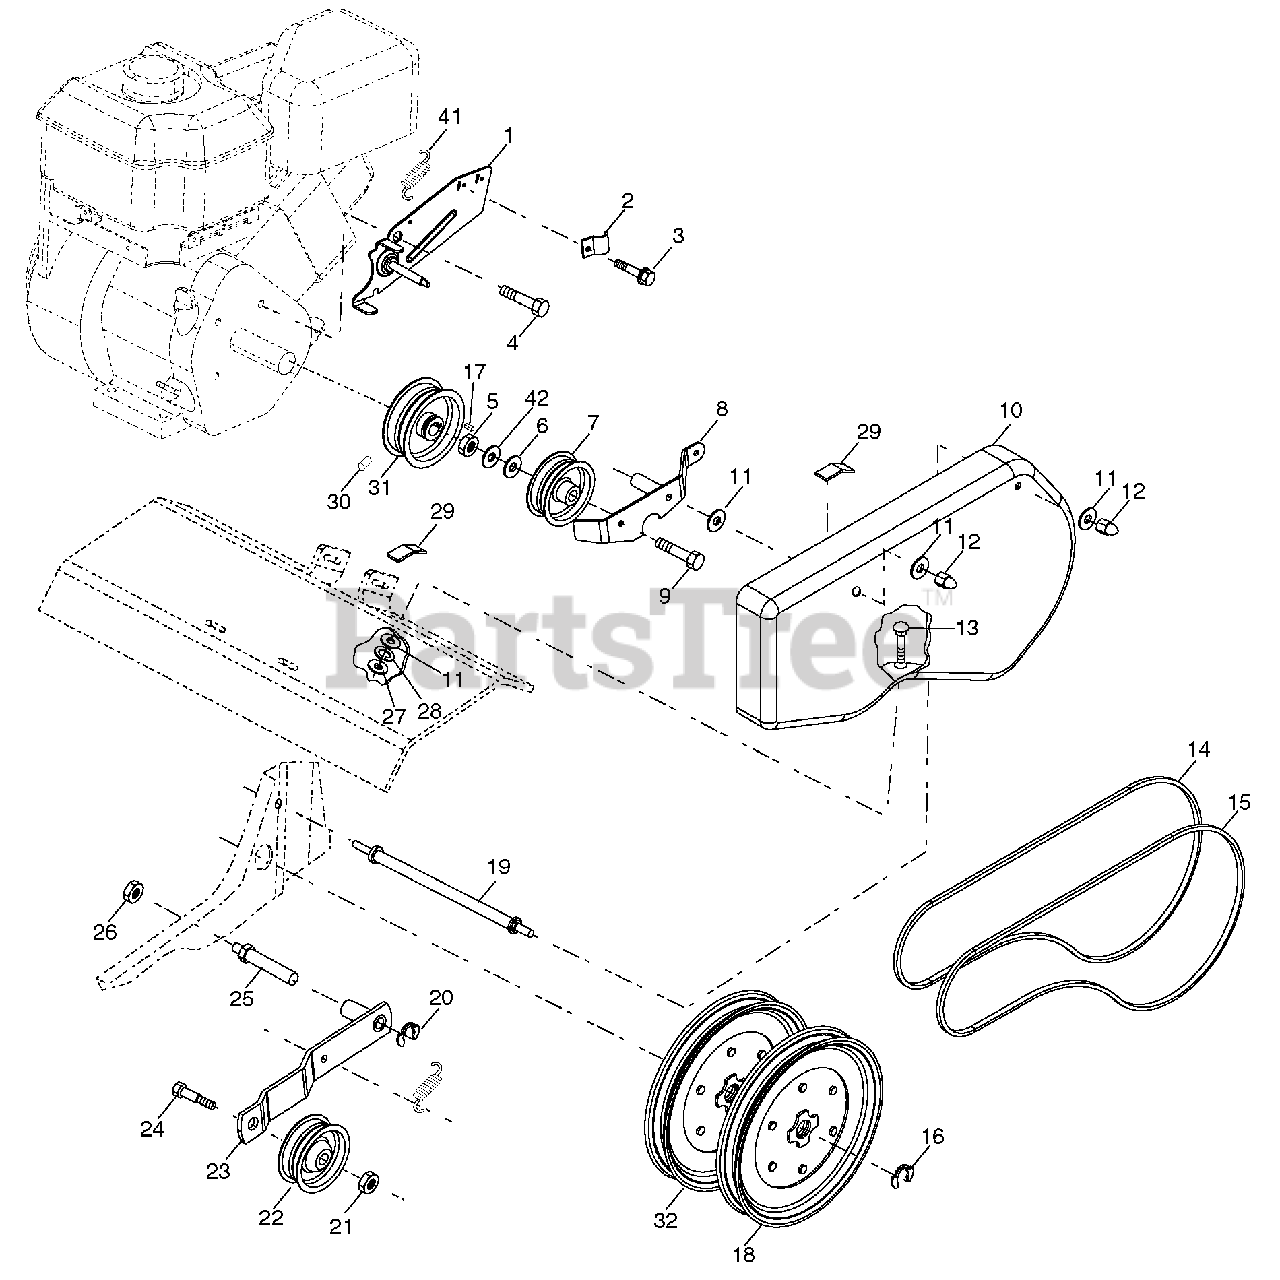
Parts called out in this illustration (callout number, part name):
1	Bracket Assembly, Belt Guard
2	Clip, Cable
3	Screw, Hex Washer Head, Slotted, Thread Cutting #10-24 x 1/2
4	Bolt, Hex Head 1/2-20 x 3/4
5	Locknut, Hex 3/8-16
6	Washer 13/32 x 13/16 x 16 Gauge
7	Pulley, Idler, Reverse
8	Reverse Idler Arm Assembly
9	Bolt, Hex Head 3/8-16 x 1-3/4
10	Guard, Belt
11	Washer 9/32 x 5/8 x 16 Gauge
12	Nut, Hex, Cap 1/4-20
13	Bolt, Carriage 1/4-20 x 3/4
14	V-Belt (Forward Motion)
15	V-Belt (Reverse)
16	Ring, Retainer
17	Key, Square
18	Pulley, Flat, Transmission
19	Bolt, Belt Guard
20	Ring, Klip
21	Nut, Hex, Jam 3/8-16
22	Pulley, Idler
24	Bolt, Hex Head 3/8-16 x 1-1/4
25	Shaft, Idler Arm
26	Nut, Hex, Jam 5/16-18
27	Nut, Hex 1/4-20
28	Washer, Lock, HH Spring 1/4
29	Pad, Idler
30	Set Screw, Headless, C.P. 1/4-20 x 1/4
31	Sheave, Engine
32	Pulley, V-Groove, Transmission
41	Spring
42	Spacer
